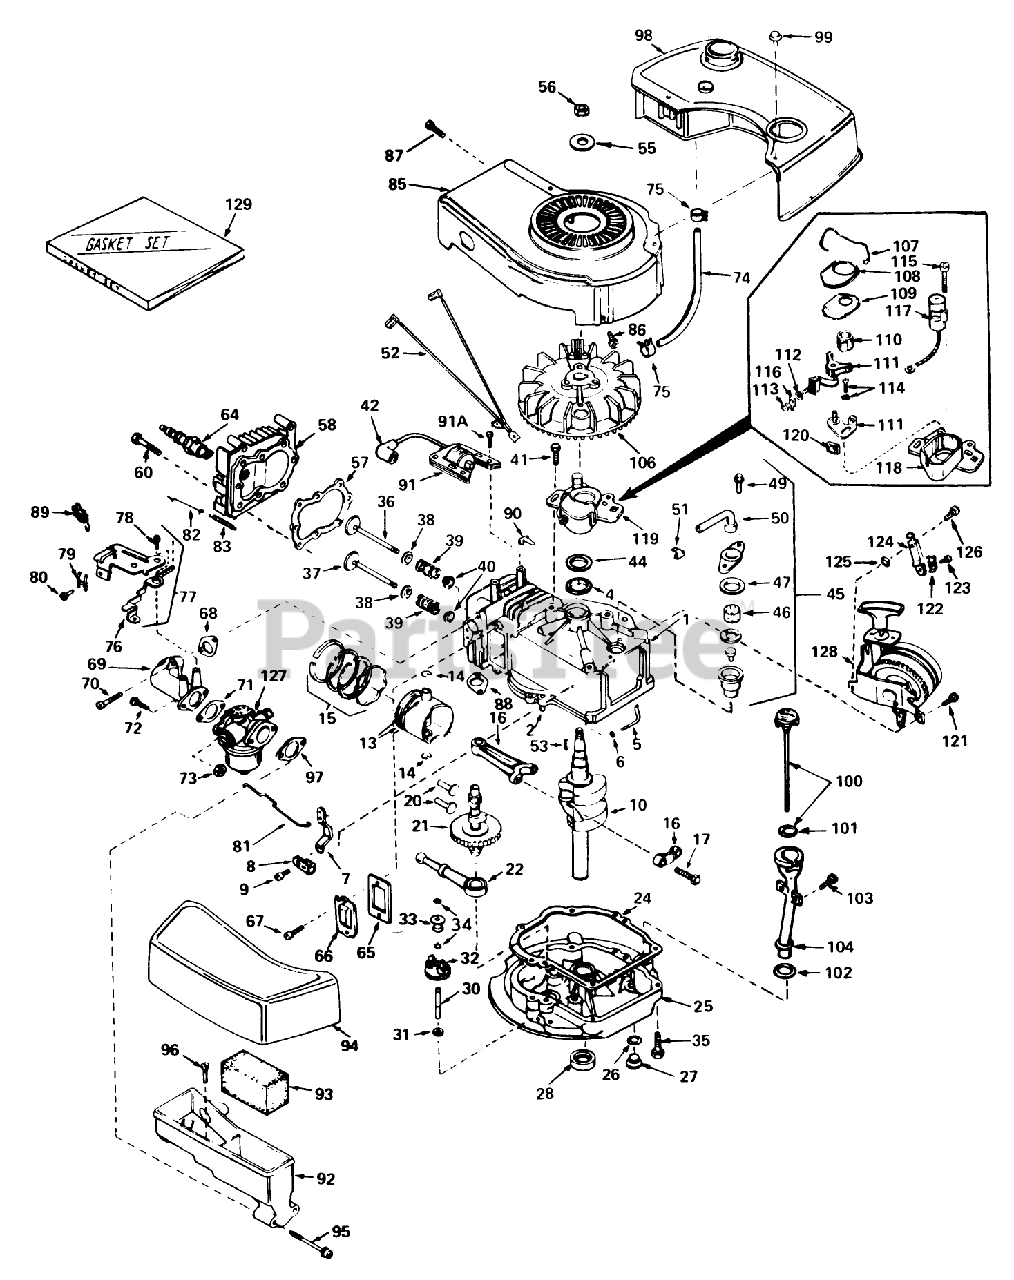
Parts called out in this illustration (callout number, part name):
1	Cyiinder Assy. (Incl. Ref. #2, 4 105)
1	Throttle Shaft and Lever ASM
2	Pin-Dowel
3	Throttle-Shutter
4	Seal-Oil
4	Screw-Shutter
5	Rod, Governor (Incl. No. 36)
5	Spring, Return
6	Washer-Flat
6	Seal-Dust
7	Governor Lever
7	Washer-Seal, Dust
8	Clamp-Lever, Governor
8	Retainer, Seal
9	Screw
9	Primer Assy.
10	Crankshaft
11	Plug-Welch, Atmospheric Vent
12	Inlet Needle, Seat Clip Assy. (Incl. No. 13)
13	Piston Pin Assy. (Incl . Ref. . #14) (Std.)
13	Piston, Pin Ring Assy. (Std.)(Incl. Ref. #13A, 14 15)
13	Piston Pin Assy. (Incl. Ref. #14) (.010 Oversize)
13	Piston,Pin Ring Assy. (.010 over-size)(Incl. Ref. #13A, 14 15)
13	Piston Pin Assy. (.020 oversize) (Incl. Ref. #14)
13	Piston, Pin Ring Assy. (Incl. Nos. 13A, 14 15)(.020 oversize)
13	Clip-Spring
14	Ring-Retaining, Piston Pin
14	Float
15	Ring Set Piston (Std.)
15	Ring Set Piston (.010 Oversize)
15	Ring Set Piston (.020 Oversize)
15	Shaft-Float
16	Rod Assy., Connecting (Incl. Ref. #17)
16	Bowl Float
17	Bolt-Rod, Connecting
20	Lifter-Valve
21	Camshaft(Mech.Comp. Release)
21	Gasket-Bowl
22	Oil Pump ASM
22	Nut-Float Bowl
24	Gasket, Mounting
25	Flange Assy., Mounting (Incl. Ref. #26thru 30)
25	O Ring-Bowl, Float
26	Gasket-Oil Drain
26	Fitting-Fuel
27	Plug Oil Drain
28	Seal Oil
30	Shaft-Governor
31	Washer-Flat
32	Governor Gear ASM
33	Spool-Governor
34	Ring-Retaining
35	Screw (1/4-20 x 1-1/4)
36	Valve, Intake (Incl. Ref. #38, 39 40) (Std.)
36	Valve, Exhaust (1/32" Oversize) (Incl. Nos. 8, 9 10)
37	Valve, Exhaust (Standard) (Incl. Nos. 8, 9 10)
37	Valve, Exhaust (1/32" Oversize) (Incl. Nos. 8, 9 10)
38	Cap-Upper Valve Spring
39	Spring-Valve
40	Cap-Valve, Spring
41	Screw
42	Cover-Spark Plug
44	Gasket Stator
45	Breather Assy. (Incl. Ref. #46, 47, 49, 50 51 )
46	Element-Breather
47	Gasket-Breather
49	Screw, Hex Hd. w/Conical
50	Tube, Breaker
51	Clip, Breather
52	Wire Ground
53	682488 LB GRASS HI-
55	Washer-Belleville
56	Nut-Flywheel
57	63573 GIL 42 SNWTHW
58	Head-Cylinder
60	Screw (5/16-18x1-1/2)
64	Plug, Spark (J17LM or equiv.)
64	Plug, Spark (Champion RCJ-8)
65	Gasket-Breather
66	Cover-Valve
67	Screw
68	Gasket, Intake
69	Pipe, Intake
70	Screw (1/4-20 x 1)
71	Gasket-Carburetor
73	Nut and Lock Washer (1/4-28)
74	Line-Fuel
75	Clamp-Line, Fuel
76	Lever Control
77	Control Assy., Speed (Incl. Nos, 76, 78 89)
78	Screw, Hex Washer Hd Shoulder Self-Tap
79	Conduit
80	Screw (10-32 x 3/8)
81	Link-Throttle
82	Link Governor Spring
83	Spring Governor
85	Housing Blower
86	Screw
87	Screw (10-24 x 9/16)
88	Gasket Exhaust
89	Terminal
90	Clip-Wire
91	Lamination Coil Assy. (Incl. No. 42)
91A	Screw
92	Body Air Cleaner
93	Filer, Air
94	Cove, Air Cleaner
95	Screw Fil Hd.
96	Screw, Hex Hd.
97	Gasket-Air Cleaner
98	Tank, Fuel
99	Screw (10-32 x 35/64)
100	Dipstick, Oil (Incl. Ref. #101)(Twist Lock)
101	O-Ring
102	Gasket
103	Screw (10-32 x 1/2)
104	Tube-Oil Fill
106	FIywheel
107	Spring Breaker Box
108	Cover-Dust
109	Gasket-Dust Cover
110	Cam-Breaker
111	Breaker Assy.
112	Washer
113	DECAL
114	Breaker Screw
115	Condenser Screw
116	Terminal, Ground
117	Condenser
118	Stator Plate
119	Stator Plate Assy. (incl. Nos. 107, 111 thru 118 120)
120	Felt,Cam Wiper
121	Screw (1/4-20 x 1/2)
122	Conduit
123	Screw (10-32 x 3/8)
124	Bracker
125	Washer
126	Screw (1/4-20 X 5/8)
127	Carburetor (Incl. Ref. #71 )
128	Starter
129	53024/VAR.16HP O/P
